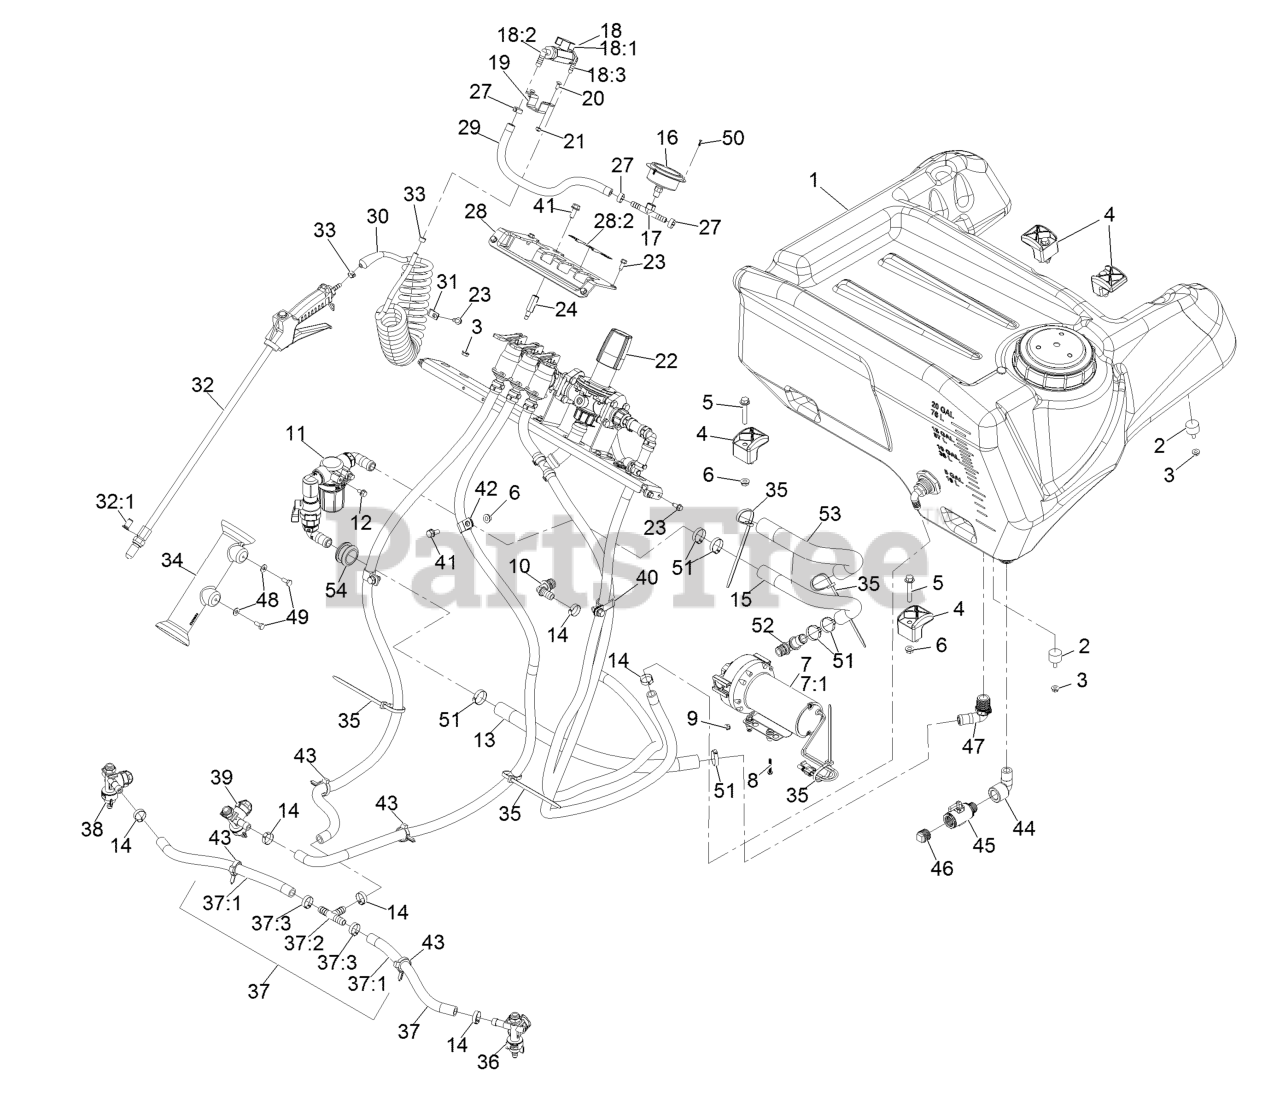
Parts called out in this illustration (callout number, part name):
1	Tank-Sprayer
3	Nut-Hex Flg
5	Screw-HHF
6	Nut-Hex Flg
7	Pump-Diaphragm, 3.8 GPM
7:1	Kit-Diaphram Pump
8	Screw-SHWH
10	Fitting-Elbow, Barbed
11	Strainer ASM
12	Screw-HHF
13	Hose-Water
15	Hose-Water
16	Gauge-Pressure
17	Fitting-Tee
18	Wand Control ASM
18:1	Valve-Ball
18:2	Fitting-Elbow-90
18:3	Fitting-Elbow-90
19	Bracket-Valve
20	Bolt-Carriage #10-24 X 1/2
21	Nut-Nyloc #10-24
22	Control Valve Manifold ASM
23	Screw-HWH 1/4-20 X .62
24	Spacer-Mount, Manifold
28	Cover-Controls
28:2	Decal-Control, Lever
29	Hose-Water, 3/8 Pvc Red
30	Hose-Coiled
31	Clamp-R
32	Spray Wand ASM
32:1	Strainer-Nozzle, 50M 5PSI Check
34	Holder-Wand
35	Tie-Cable 7 15/16 (Large)
36	Left Nozzle Sub ASM
37	Hose ASM
37:1	Hose-Water
37:2	Fitting-Tee
38	Right Nozzle Sub ASM
39	Center Nozzle Sub ASM
41	Screw-HHF 5/16-18 X 3/4 SS
42	Clip-Loom 5/8
43	Clamp-Hose
44	Elbow-90 DEG
45	Microvalve
47	Elbow-Hosebarb
48	Washer-Flat
49	Screw-HH 1/4-20 X 5/8 SS
50	Screw-TAP
52	Fitting-Elbow
53	Sleeve-Corrugated, Split
54	Grommet
